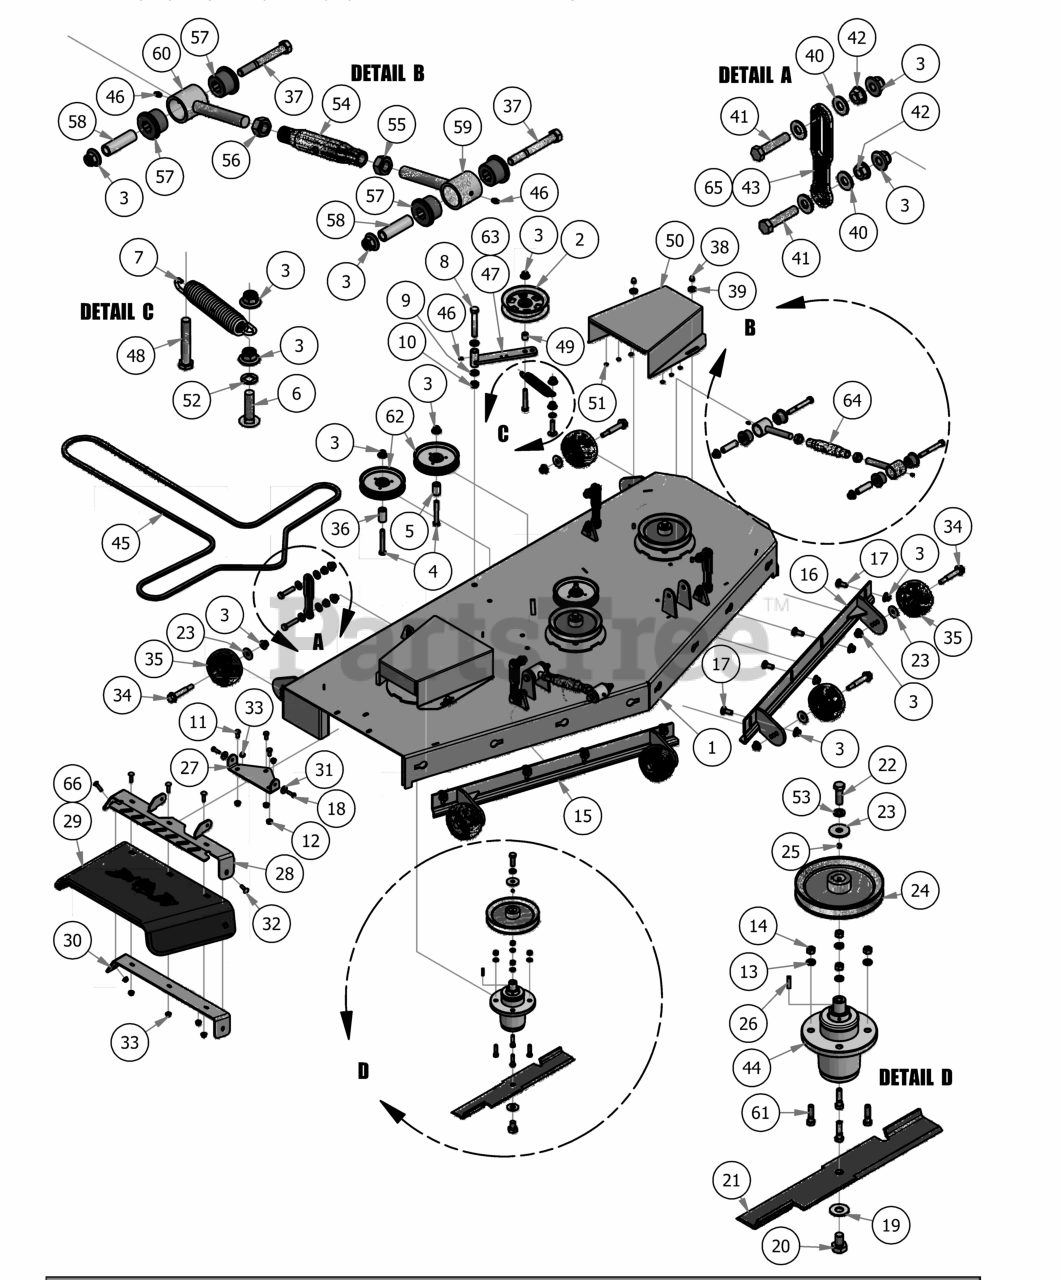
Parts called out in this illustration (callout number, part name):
1	2015 72" Deck
2	5" Idler Pully
3	1/2-13 Nylon Flange Nut
4	1/2 x 3 1/2 Flange Bolt Grade 8
5	Idler Pulley Standoff
6	1/2 x 2" Carriage Bolt
7	Deck Idler Spring
8	5/8" x 4" Hex Bolt
9	.630 ID Plastic Washer
10	5/8-11 Nylon Insert Jam Half Nut
11	3/8" x 3/4" Hex Bolt
12	3/8" Flange Nut
13	3/8 Lockwasher Zinc
14	3/8-16 Hex Nuts Zinc
15	72" Deck Adustable Front (Right)
16	72" Deck Adjustable Front (Left)
17	1/2" x 1 1/4 Carriage Bolt
18	5/16" x 1" Bolt
19	5/8'' Flat Washer
20	5/8" x 1 1/2" Grade 8 Hex Bolt (Fine)
21	72" High Lift Fusion Blade
22	1/2"-20 x 1 1/2 - Grade 5 Fine Thread Bolt
23	1/2" Belleville Washer
24	7" Deck Pulley
25	5/16 Set Screw
26	1/4" x 1" Key
27	Discharge Chute Hanger (deck mounted)
28	60" Discharge Chute Upper Hanger
29	Rubber Discharge Chute
30	60" Discharge Lower Bracket
31	.360 ID Plastic Washer
32	5/16" x 1 1/4" Carriage Bolt
33	5/16" Nylock Flange Nut Zinc
34	Deck Wheel Bolt
35	Anti-Scalp Roller
36	1 3/4" Pulley Spacer
37	1/2" x 4" Bolt (Grade 8)
38	Acorn nut-pulley Cover
39	.360 ID Plastic Washer-Black
40	.505 Nylon Spacer
41	1/2-13X 2-1/4 GR Hex Bolts
42	1/2" Flange Nut
43	Deck_Hanging_Tab
44	OUTLAW SPINDLE ASSEMBLY
45	B202 Belt for 72" Outlaw
46	1/4" Press in Grease Fitting
47	Deck Idler
48	1/2-13 x GR 5 Hex Bolt Zinc
49	Spacer 3/4 OD x 1/2 ID x 3\4 Length
50	72 Outlaw Spindle Pulley Cover
51	Black, Round Stick-On Rubber Bumper
52	.517 Square Hole Round Washer
53	1/2" Lock Washer
54	2015 Outlaw Toplink Body
55	3/4-10 Left-Handed Hex Nuts Zinc
56	3/4-10 Hex Nuts Zinc
59	Turn Left-Handed
60	Right-Handed End
61	3/8" x 1 1/2" Hex Bolt
62	5-3/4 Idler Pulley-Capitol Stampings
63	Deck Idler Assembly - Includes parts: 2,3,46,47,48,49
64	Turnbuckle Assembly
65	Outlaw Deck Hanger Assembly - Includes Parts:3,40,41,42,43
66	Chute Assembly - Includes Parts:28,29,30,32,33
